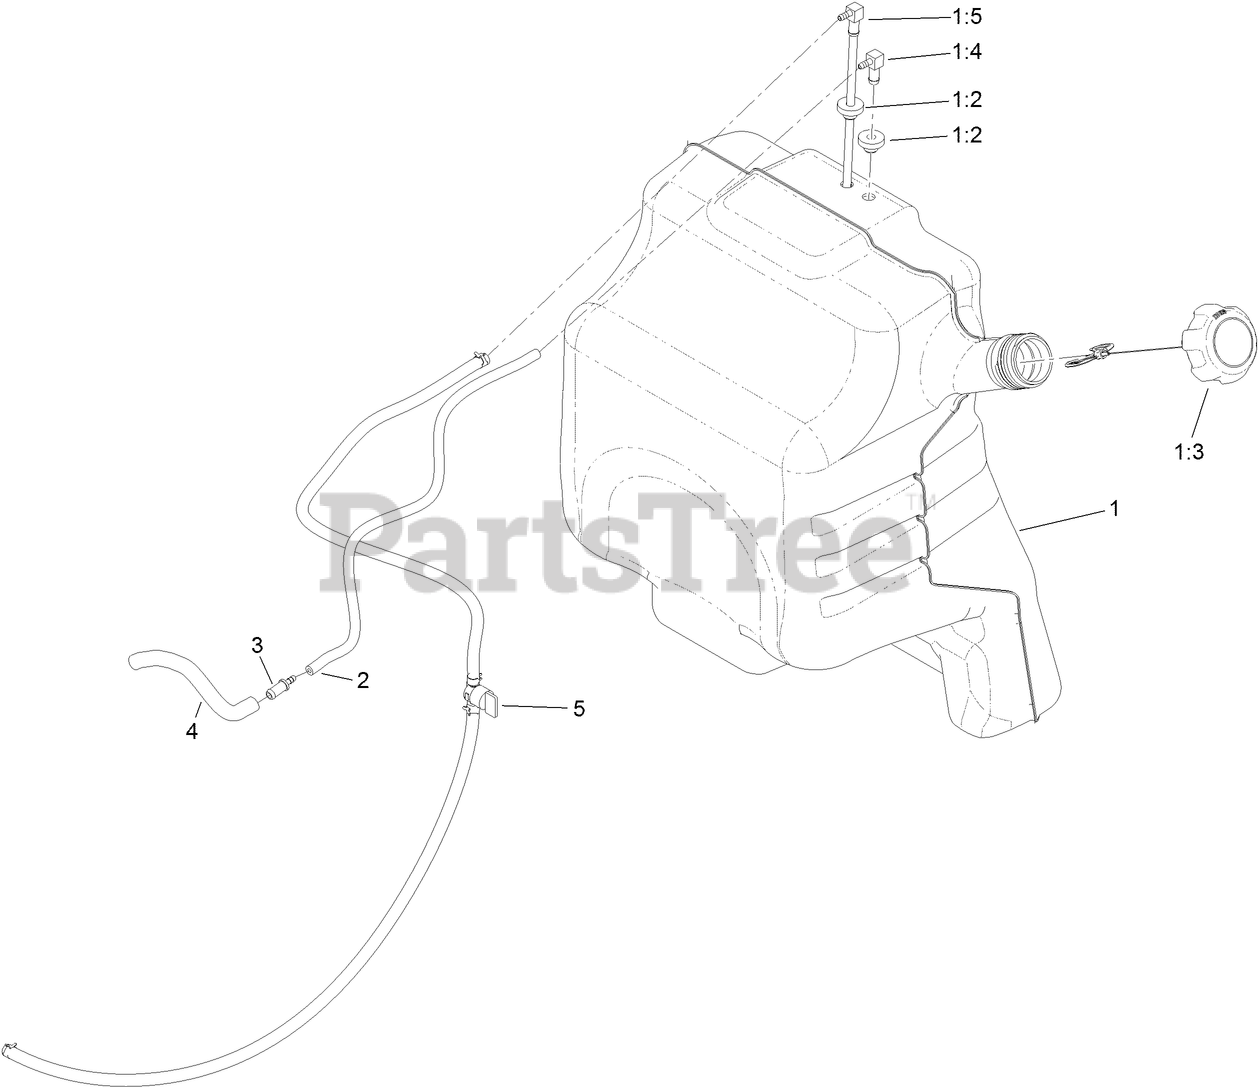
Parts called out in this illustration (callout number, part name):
1	FUEL TANK ASM
1:2	BUSHING
1:3	CAP-FUEL
1:4	FITTING-ELBOW, 90 DEG
1:5	ASM, TUBE-FUEL
2	HOSE-FUEL
3	FITTING-STRAIGHT
4	HOSE-FUEL
5	ASM-FUEL LINE
